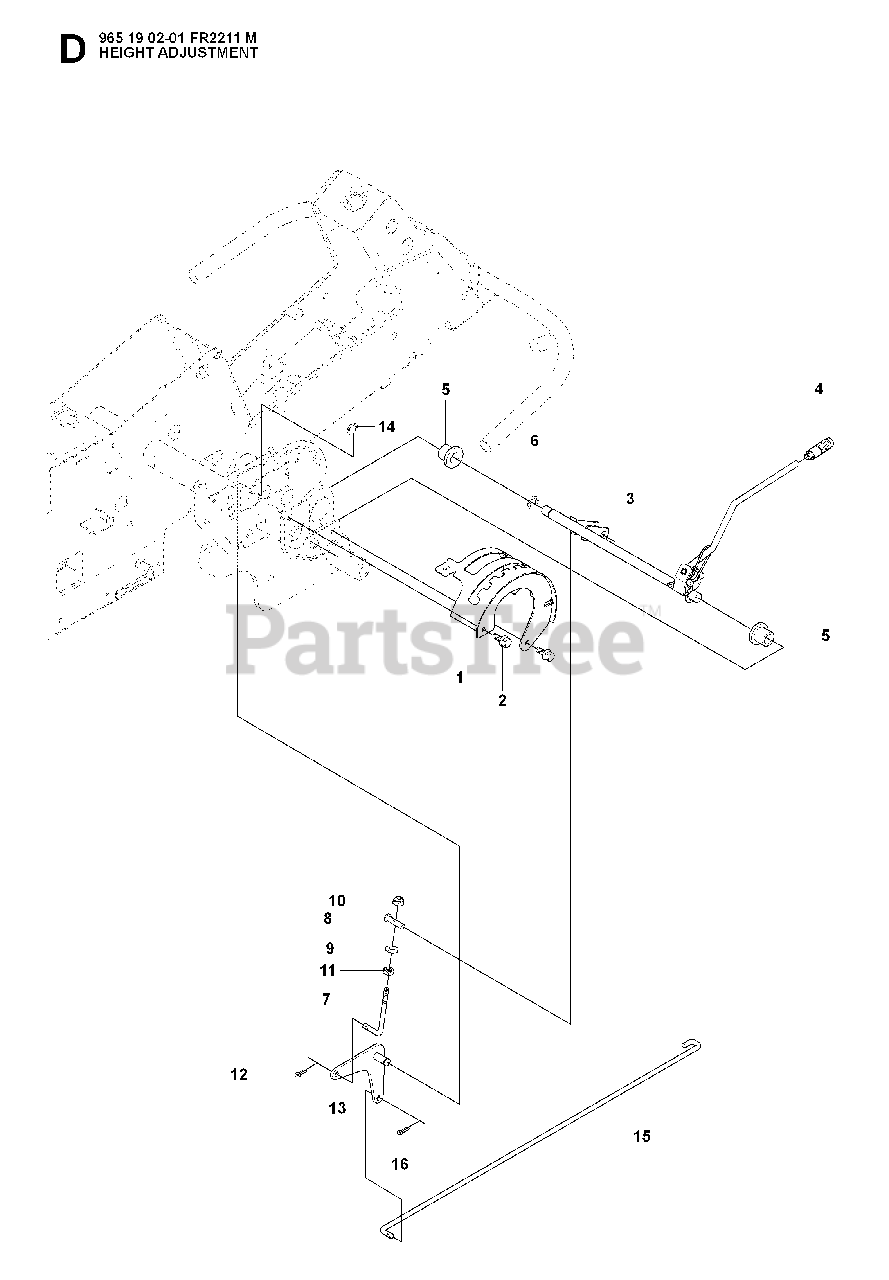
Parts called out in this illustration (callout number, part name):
4	GEAR STICK KNOB
5	BUSHING
9	WASHER
10	LOCKNUT M8
11	NUT
12	SPLIT PIN
14	RETAINING RING
16	SPLIT PIN
